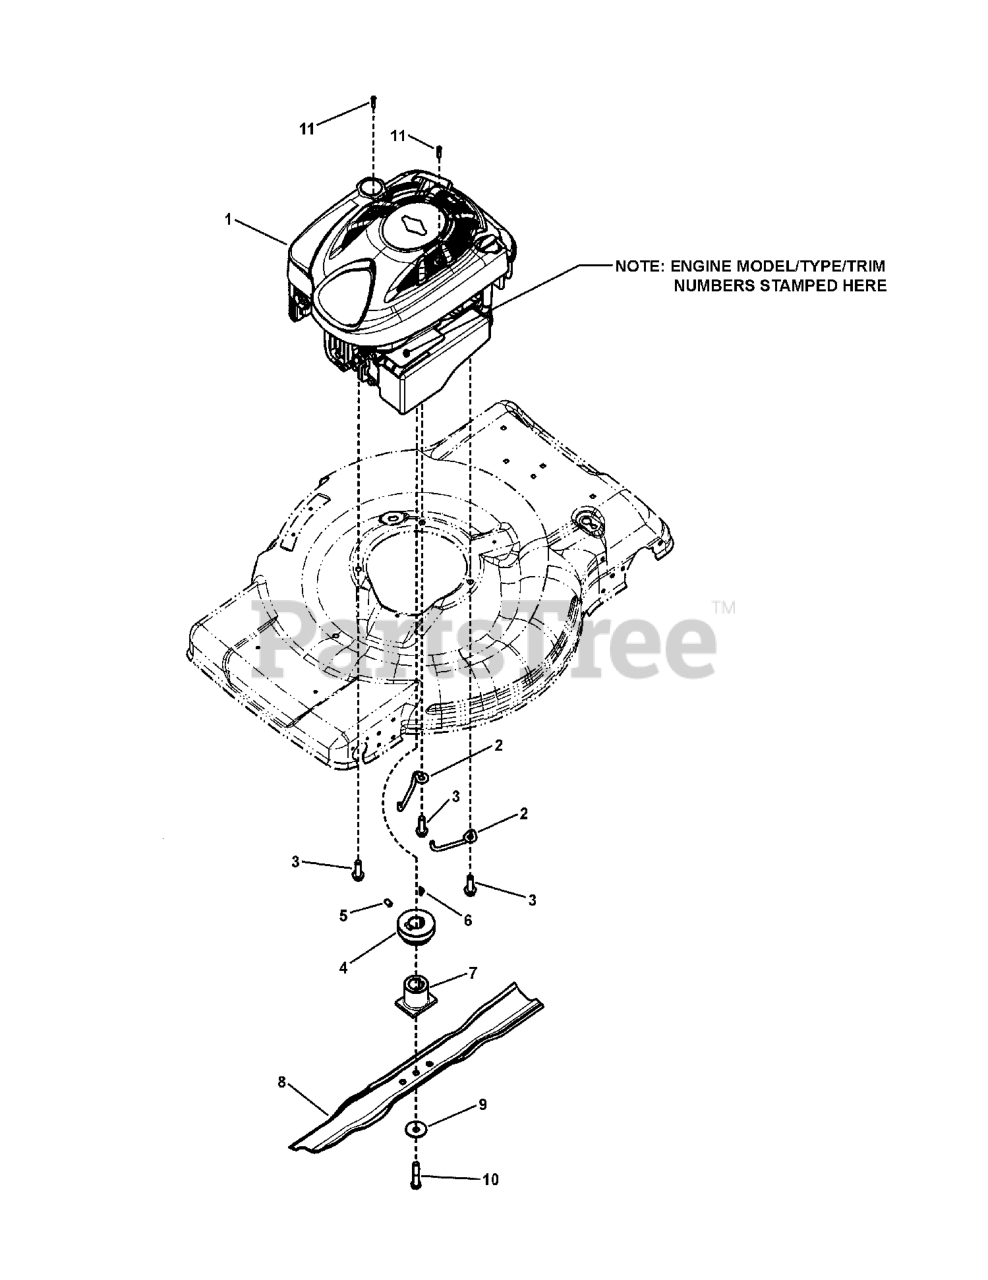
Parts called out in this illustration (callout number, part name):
1	* ENGINE, B&S 700 SER, ES, X-SPEC
2	BELT GUIDE, Engine, FWD
3	HWST, 3/8-16 x 1.25
4	PULLEY, Engine
5	SET SCREW, 5/16-18 x 1/2" Hex Recess
6	KEY, #HP-506 Hi-Pro
7	HUB, Blade
8	BLADE, 22" Wave
9	WASHER, Cone
10	HHCS, 3/8-24 x 2 GR 5
11	SCREW, Pan HD Cross Recess, Tapping
